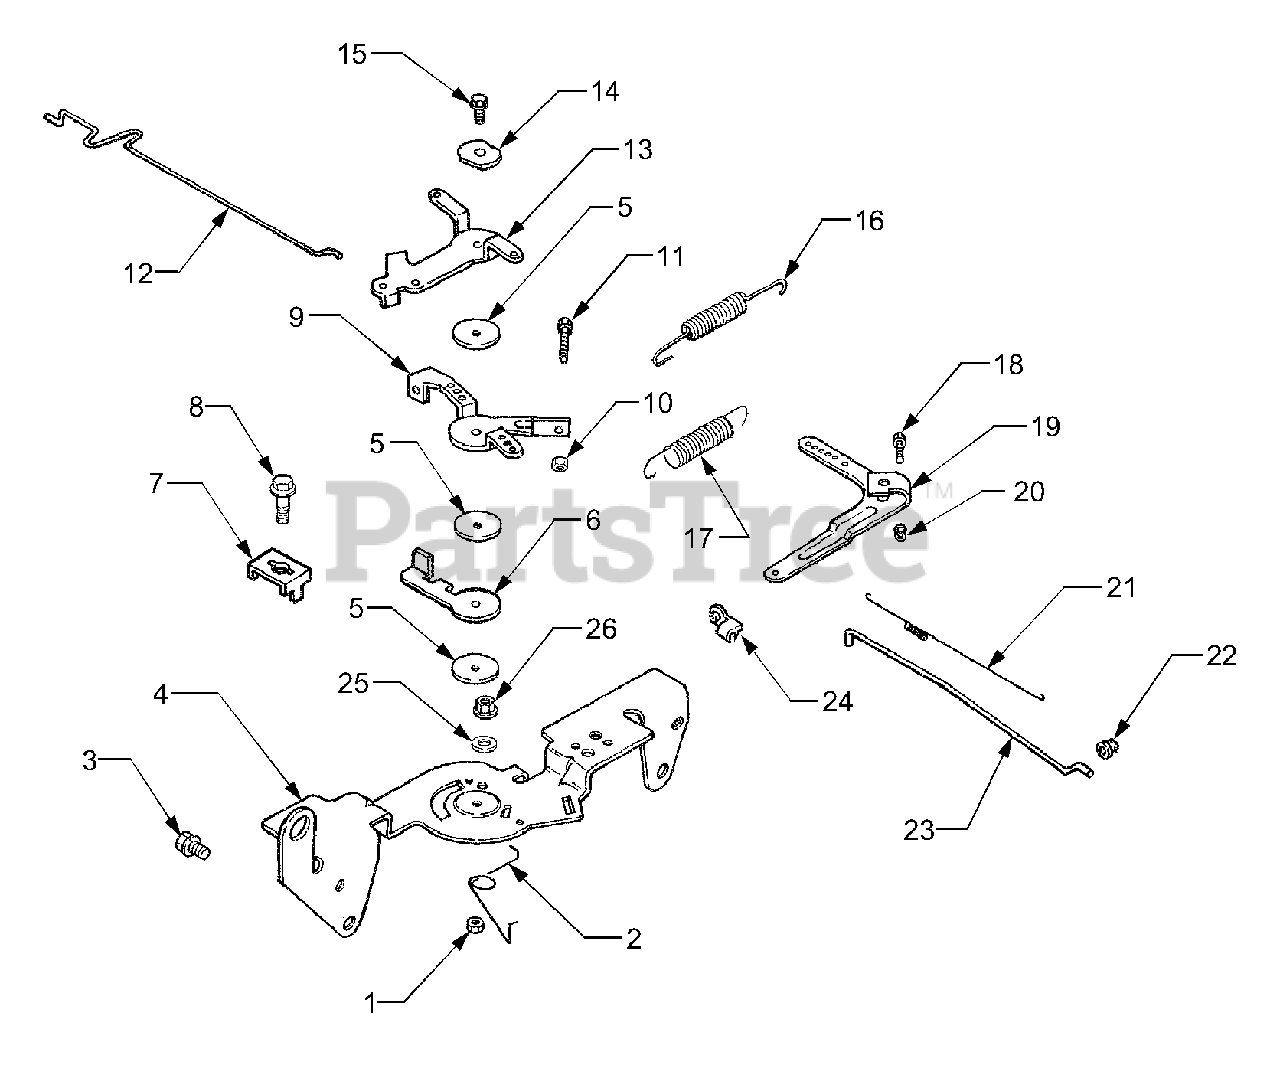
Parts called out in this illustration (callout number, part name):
1	Nut, Hex Lock M5 x 0.8
2	Spring, Choke Return
3	Screw, Hex Flange M6 x 1.0 x 16
4	Bracket, Control
5	Washer , Plain 5.5mm
6	Lever, Throttle Actuator
7	Clamp, Cable
8	Screw, Hex Flange M5 x 0.8 x 16
9	Lever, Throttle Control
10	Nut, Hex M4 x 0.7
11	Screw, Hex Cap M4 x 0.7 x30
12	Linkage, Choke
13	Lever, Choke
14	Washer, Spring 1/4"
15	Screw, Hex Flange M5 x 0,.8 x 20
16	Spring, Throttle Limiter
17	Spring, Governor
18	Screw, Round Hd. Square Neck
19	Lever, Governor
20	Nut, Hex Flange M6 x 1.0
21	Spring, Linkage
22	Bushing, Linkage Retaining
23	Linkage, Throttle
24	Bushing, Linkage Retaining
